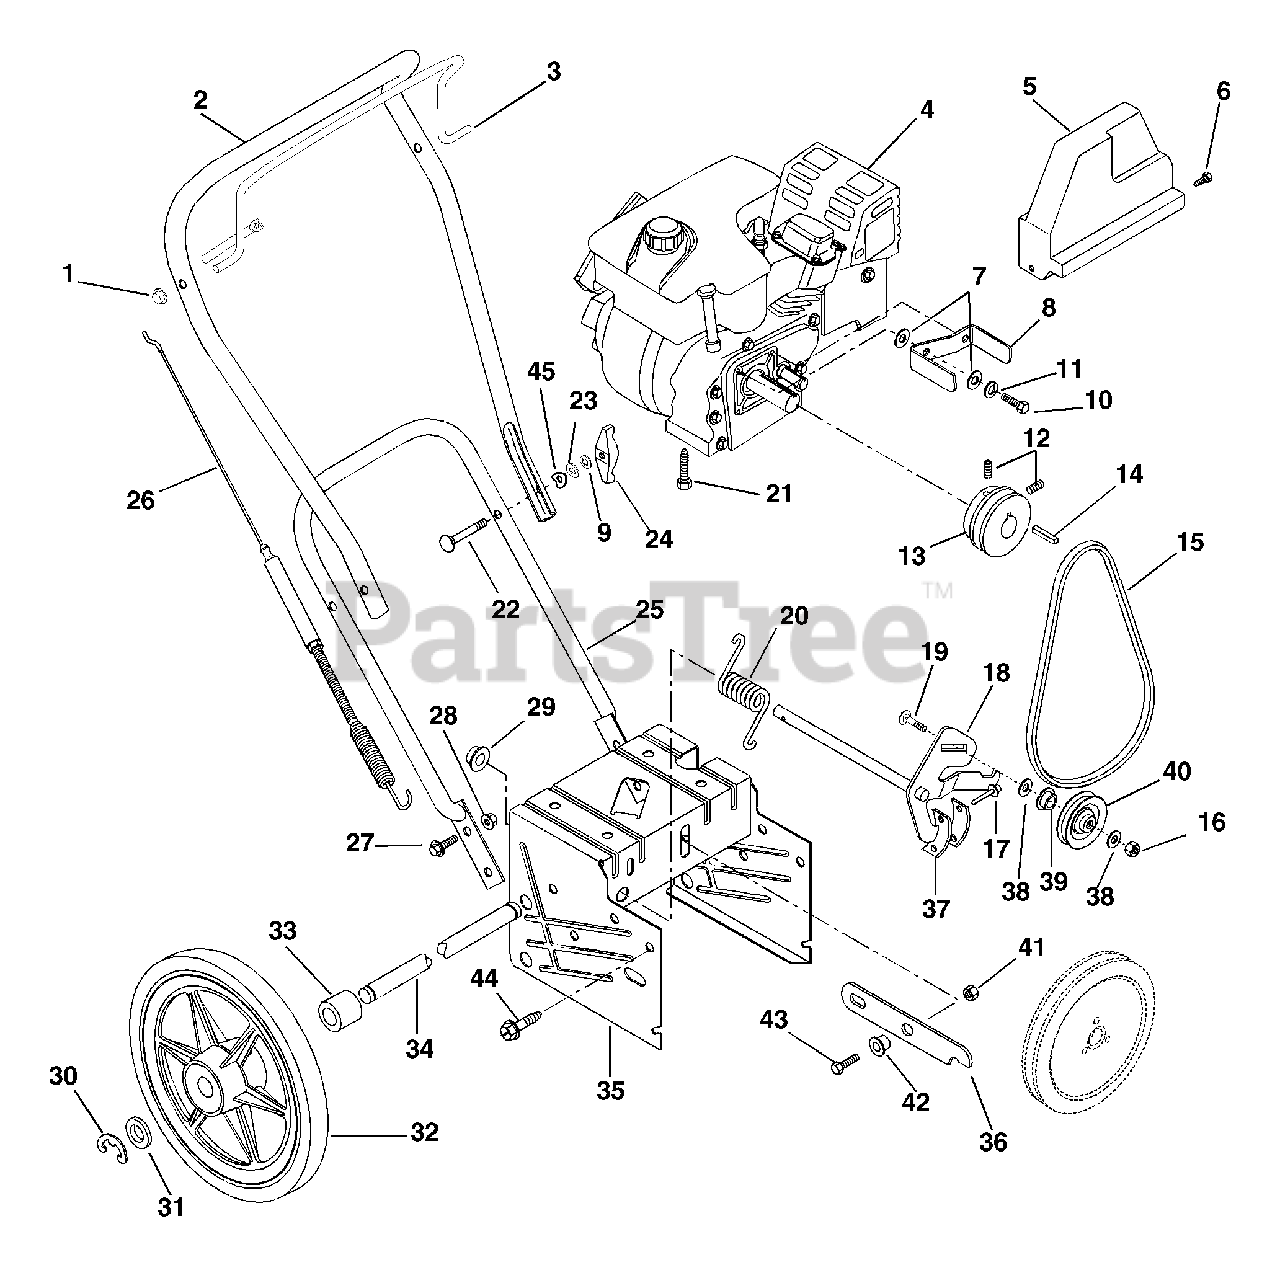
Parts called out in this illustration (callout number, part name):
1	NUT-PUSH .312 DIA. PAL
2	UPPER HANDLEBAR
4	ENGINE, 5HP TEC. OHV-RECOIL
5	COVER, BELT
6	@SCR-TAP .25-20X.37 HWH YWZ TR
7	WSHR-FL-STL .328X.87X.179 YWZC
8	BELT FINGER
9	WSHR-LK .312X.097 HVY YWZC
10	BLT-HEX .31-24X.75 YWZC GR5
11	WSHR-LK .313X.093 MED HICLR
12	SCR-SET .31-18X.38 SKHCUPDL
13	ENGINE SHEAVE
14	KEY-SQ .188X1.0X.188 SAE 8630
15	V-BELT, 4L-COGGED
16	NUT-LK .312-18 GR A PL
17	RVT-TBLR .187X.437 RH ST PL
18	BRAKE CLUTCH ARM W/LINING
19	@BLT-RDHDSQNK .31-18X1.50 G5YZ
20	SG-TORS .148X1.0X1.53
21	@SCR-TAP .38-16X1.00 HWH TR YZ
22	@BLT-RDHDSQNK .31-18X2.25 G5YZ
23	WSHR-FL-STL .328X.875X.062YWZC
24	KNOB - WING .312-18 UNC
25	HANDLEBAR, LOWER
26	CABLE, AUGER DRIVE
27	BLT SERHFWH .31-18X.62 GR5YWZC
28	@NUT-SPNLK-FLG .312-18 YWZC
29	CAP, .50 ROD YWZC
30	RG-RTNG-EXT .625X.042
31	WSHR-FL-STL .562X1.156X.095 YW
32	WHEEL, 14 X 1.75 X .56
33	SPACER, AXLE .571X.755X1.815
35	FRAME, MAIN - ST 520
37	BRAKE LINING
38	@WSHR-FL-STL.38X.875X.083 YWZC
39	SPCR, BRG .315X.50X.688X.281
40	IDLER
41	@NUT-LK-CTR .25-20 YWZC
42	BSHG-FLG .265X.437X.250X.750
43	BLT-HEX .25-20X.63
44	@SCR-TAP .38-16X.50 HWH TR YWZ
45	WASHER,SADDLE-.320 X.937 X.062
